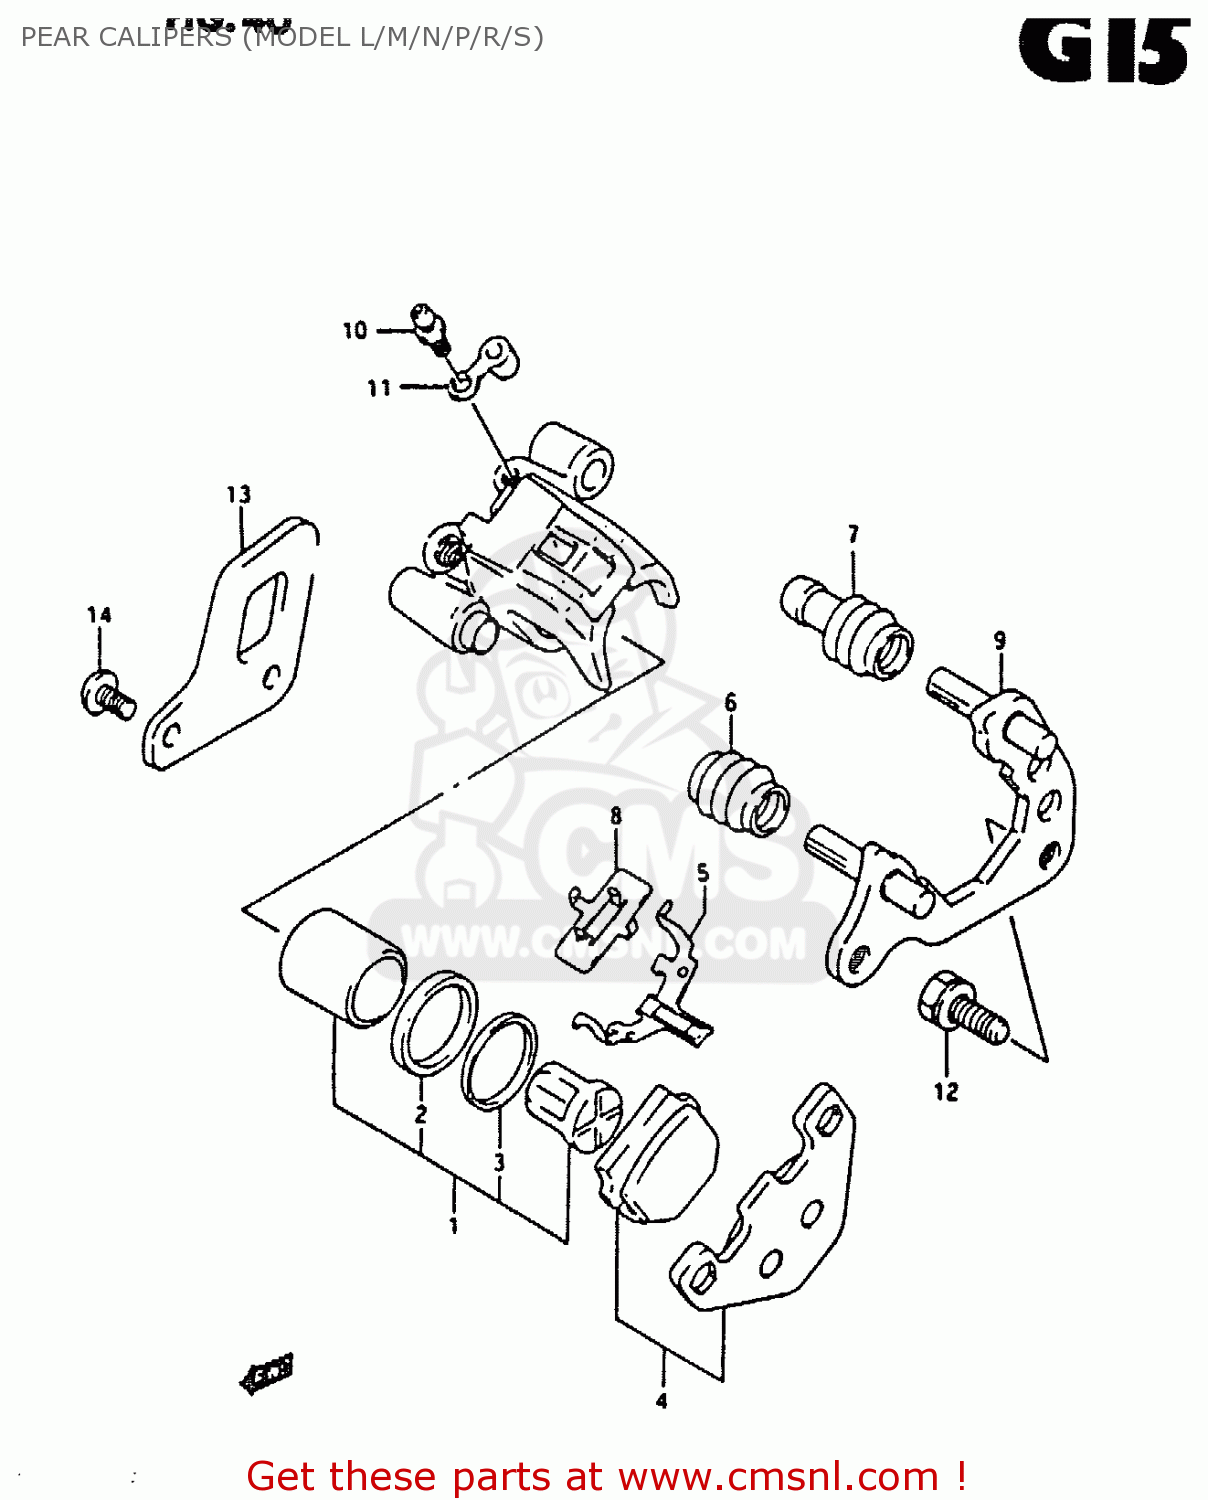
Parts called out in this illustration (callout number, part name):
1	PISTON SET
2	SEAL,PISTON
3	SEAL,WIPER
4	PAD SET (NAS)
5	SPRING,PAD
6	BOOT,AXLE
7	INSULATOR,AXLE
8	SHIM
9	CARRIER,CALIPER
10	BLEEDER
11	CAP,BLEEDER
12	BOLT(8X18)
13	GUARD,RR CALIPER
14	SCREW(6X12)
